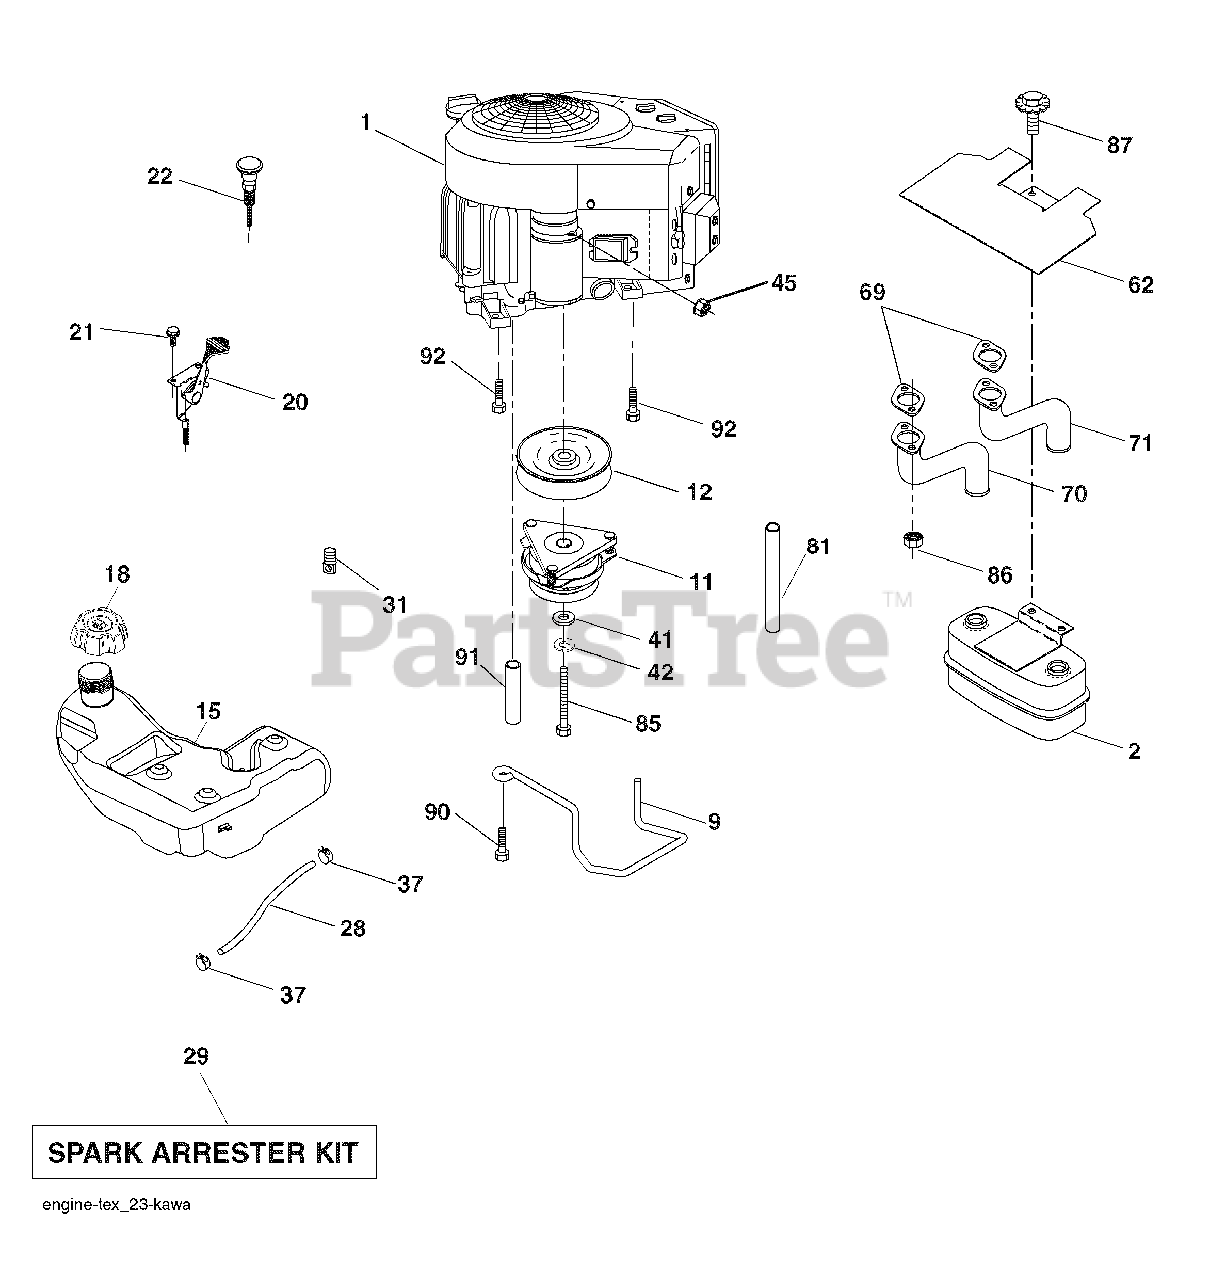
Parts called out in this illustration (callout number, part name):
9	Keeper Belt Engine
11	Clutch Electric
12	Pulley Engine
18	Cap Asm
20	Control Throttle
21	Screw 10 x .750 BOS Thread
22	Control Choke
28	Fuel Line
29	Spark Arrester Kit
31	Clip Push-In
37	Clamp Hose
41	Washer 1-1/2 OD x 15/32 ID x .250
42	Washer Lock 7/16
45	Nut Keps Hex 1/4-20 unc
62	Shield Heat Muffler
69	Gasket
70	Tube Exhaust LH
71	Tube Exhaust RH
81	Tube Drain Oil Easy
85	Bolt Hex 7/16-20 x 4-1/4 Gr. 5
86	Nut M8-1.25
87	Bolt 5/16-18 unc x 1 w/Sems
90	Screw 3/8-16 x 1
92	Screw 3/8-16 x 1
